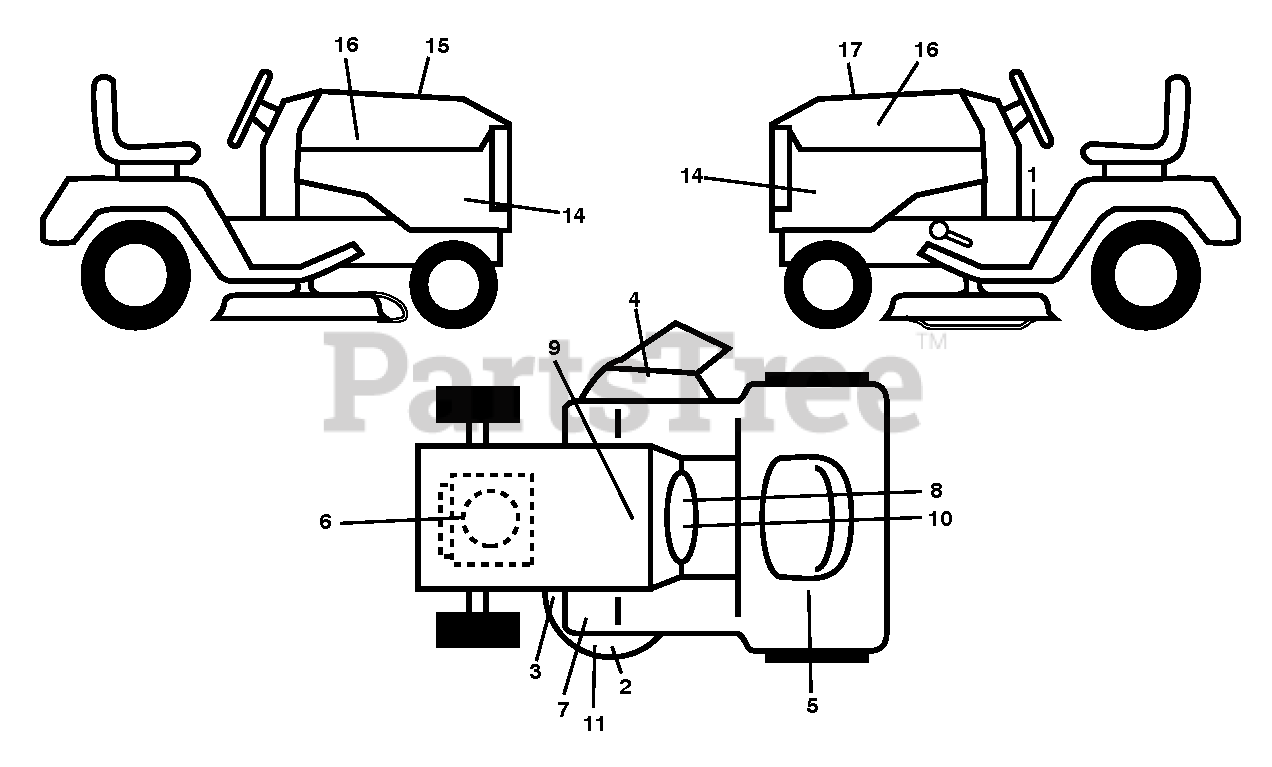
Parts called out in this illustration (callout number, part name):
1	DECAL.FENDER.WARNING.ENGLISH
2	DECAL, NO STEP
3	DECAL.MOWER.SCH.48/54
4	DECAL, CAUTION
5	DECAL.WARN.FUEL.RESERVE
6	DECAL.ENGINE.BS27.ENDU.2794718
7	DECAL.PEDAL.HUSQ.CROWN
8	DECAL, WARNING SPARK ARRESTOR
9	DECAL BTRY SYMBOLS
10	LABEL.EMISS.CALIF.HUSQVARNA
11	DECAL.HV.REINFORCED.DECKS.2012
14	DECAL.SIDE.PANEL.GT48XLS
15	DECAL.WARNING.CUST.RESP.E85.
16	DECAL.BADGE.170MM.TEXTLOGO.
